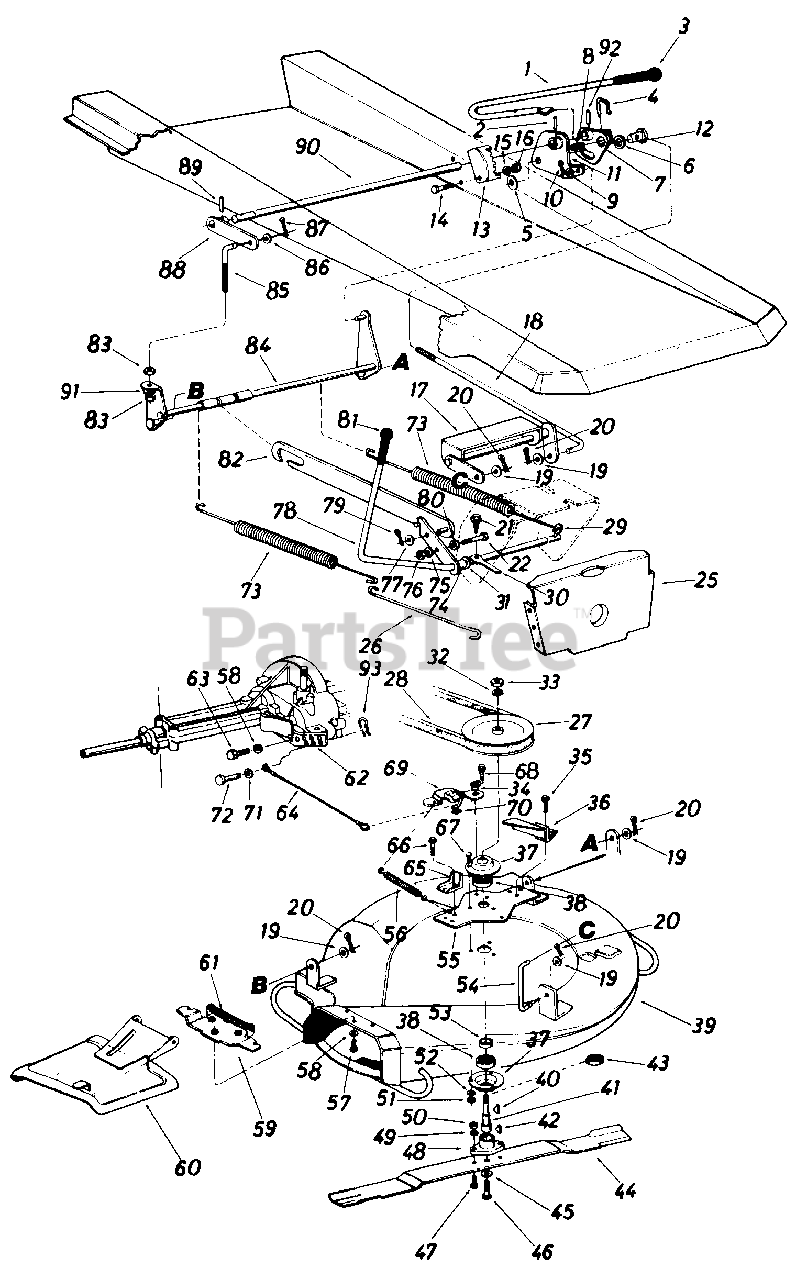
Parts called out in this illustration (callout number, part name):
1	Deck Lift Handle
2	Spring Pin Spir. 1/4" Dia. x 1.50" Lg.
4	Cotter Pin
5	Fl-Wash. 5/8" I.D. x 1.0" O.D. x .12
6	Fl-Wash. 5/8" I.D. x 1.25" O.D. x .60
7	Deck Lift Handle Brk't. Ass'y.
8	Compression Spring .50" O.D. x 1 .04
9	Fl-Wash. .385" I.D. x .87" O.D. x .06
10	Cotter Pin 1181' Dia. x 1.00'
11	Deck Lift Brk't. Ass'y. L.H.
12	Adj. Ferrule Deck Lift Hand le
13	Index Bracket
14	Hex Bolt 5/16-18 x .75" Lg.
15	L-Wash. 5/16" I.D.*
16	Hex Nut 5/16-18 Thd.
17	Deck Lift Ass'y. Front
18	Deck Lift Connecting Rod
19	Fl-Wash. .385" I.D. x .87" O.D. x .06
20	Cotter Pin 1/8" Dia. x 1.00"
21	Hex Wash. Hd. Self-Tap Scr. 1/4-20 x .50" Lg.
22	Hex Bolt 5/16-18 x 1.5" Lg.
25	Pivot Bar Bracket
26	Spring Hook
27	Deck Pulley 6.0" O.D.
28	"V"-Belt 1/2" x 52" Lg.
29	Spec. Clevis Pin .250" Dia.
30	Switch Actuator
31	Fl-Wash. .531" I.D. x .930" O.D. x .050
32	Fl-Wash. 5/8" I.D.
33	Hex Jam Nut 5/8-11 Thd.
34	Shoulder Spacer
35	Hex Wash. Hd. Scr. 5/16-18 x .62" Lg.
36	Belt Guard Ass'y.
37	Bearing Housing 1.85" I.D.
38	Ball Brg. .787" I.D. x 1.85" O.D. x .551
39	26" Deck Ass'y.
40	#61 Hi-Pro Key 3/16" x 5/8" Dia.
41	Blade Spindle
42	#6 Hi-Pro Key 5/32" x 5/8" Dia.
43	Bearing Shield
44	26" Blade
45	L-Wash. 3/8" I.D. Heavy Duty
46	Hex Bolt 3/8-24 x 1.50" Lg. Grade 5
47	Hex Bolt 5/16-24 x 1.00n Lg. Grade 5
48	Blade Adapter Kit
49	L-Wash. 5/16n l.D.
50	Hex Nut 5/16-24 Thd.
51	Hex Nut 5/16-18 Thd.
52	L-Wash. 5/16ll I.D.
53	Spacer.836" I.D. x 1.01" O.D. x .320
54	Deck Link 3 9" Lg.
55	Belt Guard Plate Ass'y.
56	Spring .38" O.D. x 3.25" Lg.
57	Hex Bolt 1/4-28 x .62" Lg.
58	L-Wash. 1/4" I.D.
59	Adapter Ass'y. Chute
60	Chute Deflector Ass'y. Comp.
61	Torsion Spring
62	Lower Inside Belt Guard
63	Hex Bolt /1/4-20 x .62" Lg.
64	Brake Cable Ass'y.
65	Belt Keeper Ass'y.
66	Hex Wash. Hd. Scr. 5/16-18 x .62" Lg.
67	Hex Sems Bolt 5/16-18 x 1.00" Lg.
68	Hex Wash. Hd. 3/8" x 75" Lg.
69	Blade Brake Brk't. Ass'y.
70	Cap Speed Nut 1/4" Rod
71	Fl-Wash. 1/4" I.D. x .501/ O.D.
72	Clevis Pin 1/4" x 1/2"
73	Extension Spring .99" O.D. x 14.2" Lg.
74	Sleeve .511" I.D. x .70"' x .37" Lg.
75	L-Wash. 5/16" I.D.
76	Hex Nut 5/16-18 Thd.
77	Fl-Wash. .385" I.D. x .87" O.D. x .06
78	Blade Engagement Lever Ass'y.
79	Cotter Pin 1/8n Dia. x 1.00" Lg.
80	Hex Nut 5/16-18 Thd.
82	Deck Drive Control Brk't. Ass'y.
83	Hex Nut 3/8-16 Thd.
84	Deck Link Ass'y. Rear
85	Deck Adj. Scr. 3/8-16 Thd.
86	Fl-Wash. .385" I.D. x 87n O.D. x .06
87	Cotter Pin 1/8n Dia. x 1.00
88	Deck Lift Brk't. Ass'y. R.H.
89	Spring Pin Spir. 1/4n Dia. x 1 50n Lg
90	Rear Height Adj. Shaft
91	L-Wash. 3/8" l.D.
92	Spring Pin Spir. 3/16" Dia. x 1.50" Lg
93	Int. Cot. Pin 5/16" Dia.
